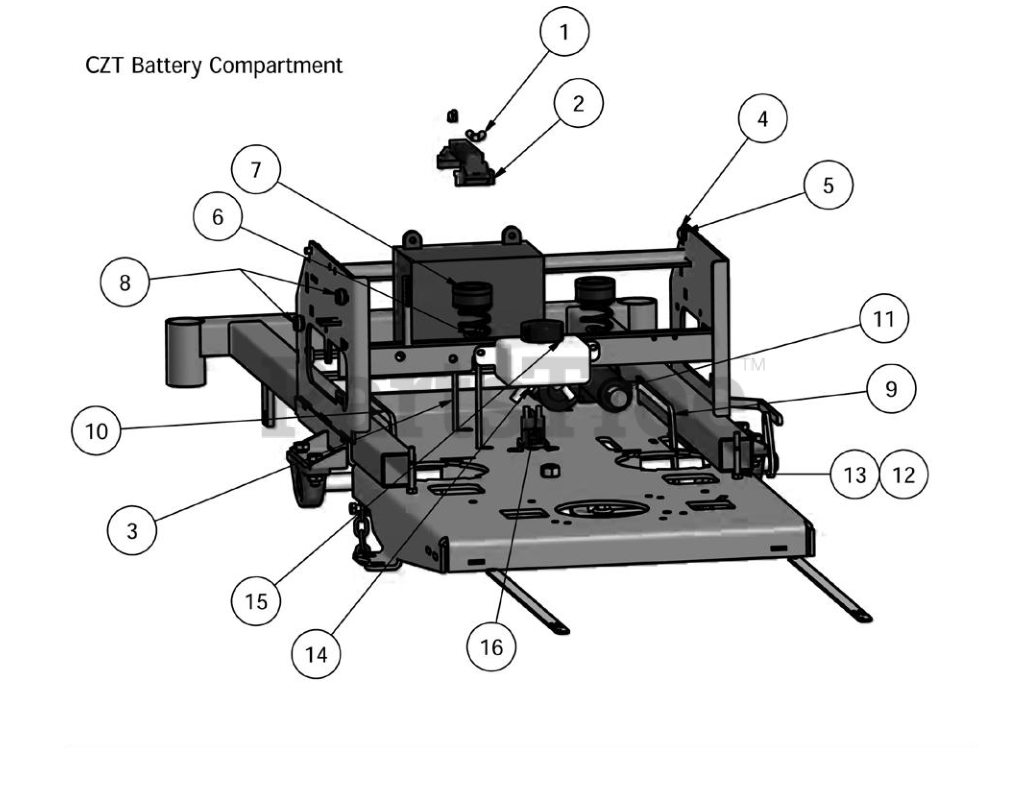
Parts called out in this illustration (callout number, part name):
1	1/4" Wing Nut
2	Battery Holder
3	Stove Bolt
4	5/16" x 3/4" Carriage bolt
5	.360 ID Plastic Washer
6	Seat Spring
7	Seat Bumper
8	1/2" Tank Spacer
9	Transaxle Drive Rod (Right)
10	Transaxle Drive Rod (Left)
11	Actuator ZT
12	5/16" x 3" Hex Bolt
14	ZT Hydraulic Tank
15	ZT Hydraulic Tank Cap
16	ZT Solenoid
